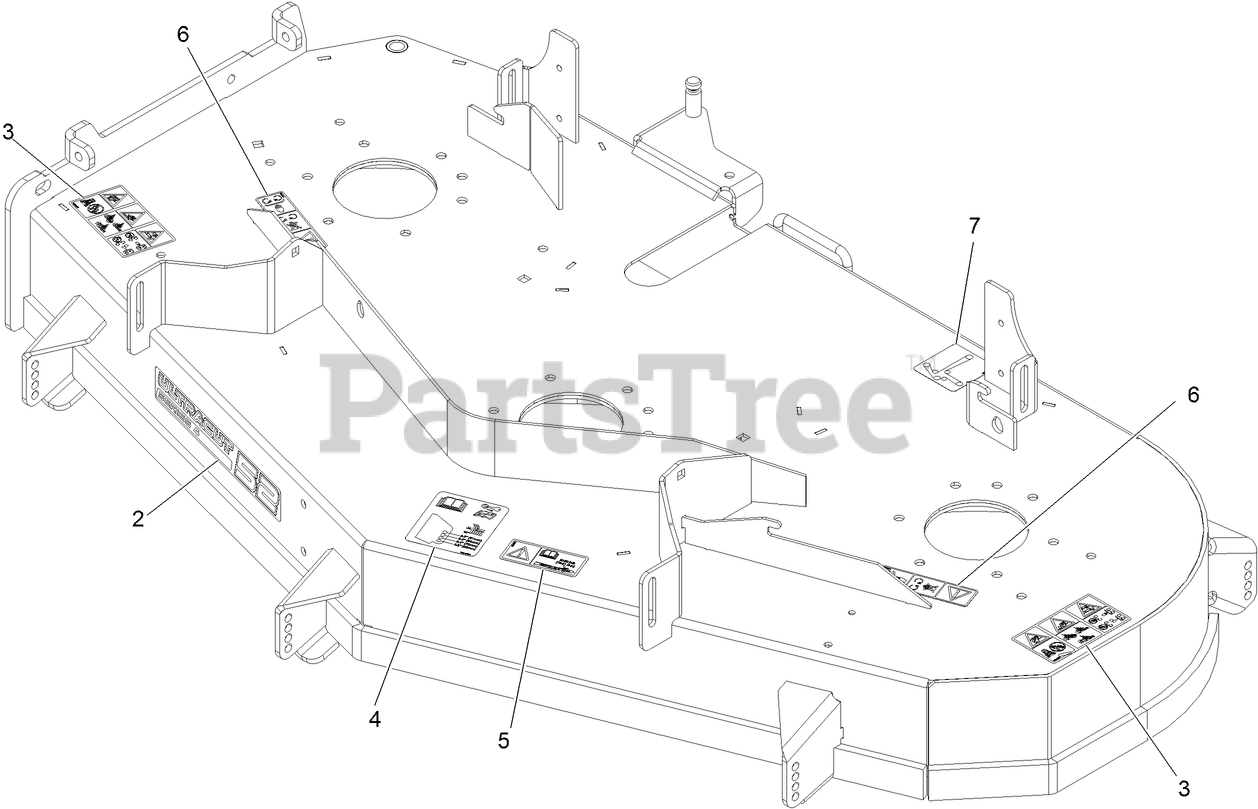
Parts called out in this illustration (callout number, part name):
2	DECAL, 524
3	DECAL-DANGER THROWN OBJECTS
4	DECAL-ROLLER, ANTI-SCALP
5	DECAL-TORQUE, BOLT
6	DECAL-COVER, MISSING
7	DECAL-ROUTING, BELT
